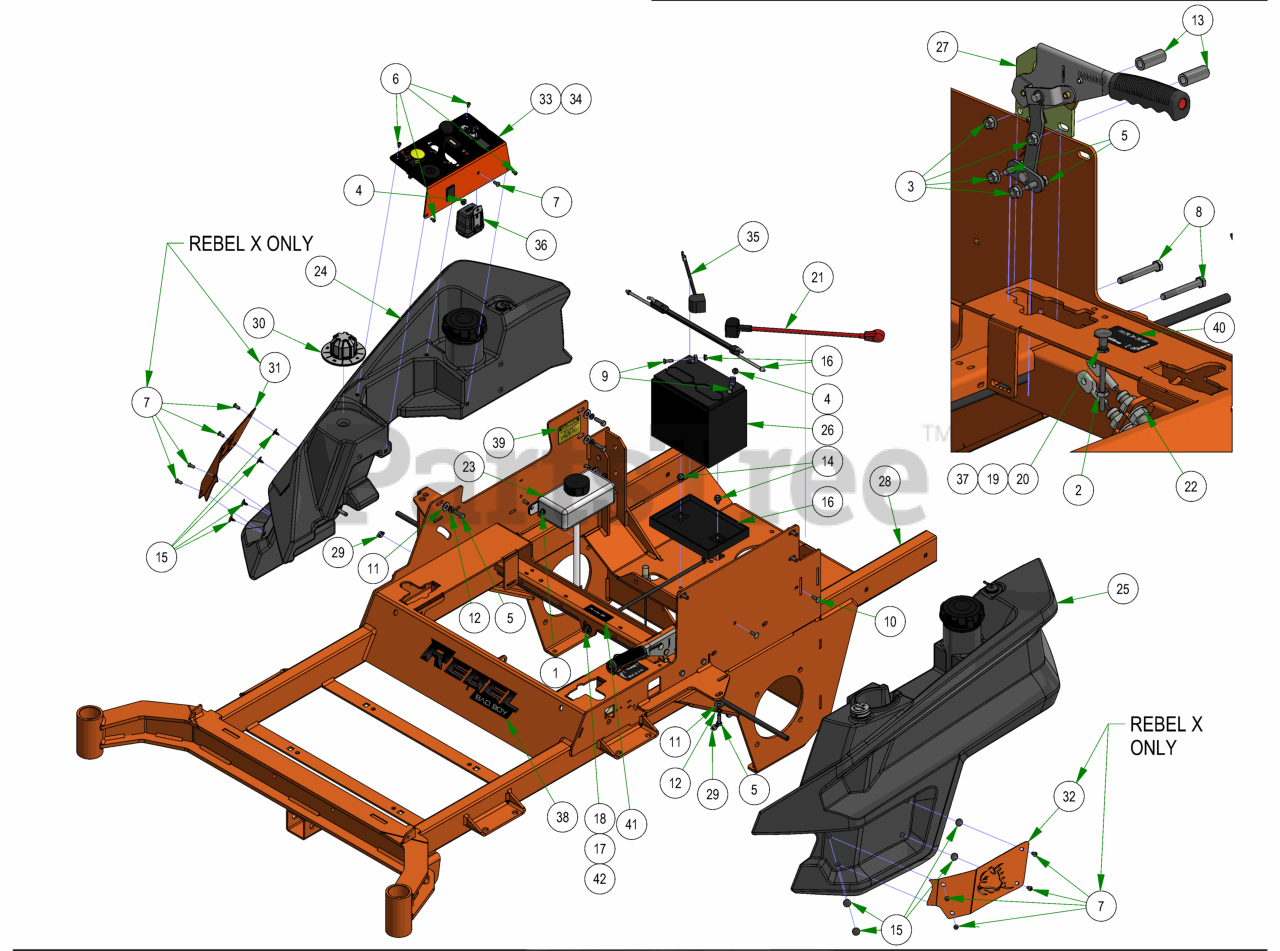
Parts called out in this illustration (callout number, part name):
1	1/4-20 NYL INSERT FLANGE LOCKNUT ZINC
2	3/8-24 HEX NUT ZINC YELLOW
3	5/16-18 NYLON INSERT FLANGE LOCKNUT ZINC
4	1/4-20 HEX SERRATED FLANGE NUT HARD/ZINC
5	5/16-18 X 1 HEX CAP SCREW (GR.5) ZINC
6	10-32 X 3/8 BUTTON SOCKET CAP SCREW 18-8 STAINLESS STEEL
7	1/4-20 X 1/2 BUTTON SOCKET CAP SCREW 18-8 STAINLESS STEEL
8	5/16-18 X 2-1/2 HEX CAP SCREW (GR.5) ZINC
9	1/4-20 X 3/4 HEX CAP SCREW (GR.5) ZINC
10	1/4-20 X 3/4 CARRIAGE BOLT (GR.5) ZINC
11	5/16 USS FLAT WASHER (7/8 OD) ZINC
12	5/16 SPLIT LOCKWASHER ZINC
13	.380 ID X .625 OD X 1.500 LGTH 2019 OUTLAW BRAKE HANDLE SPACER ZINC
14	5/16-18 X 1/2 HWH unslot (F) tcs zinc
15	3/16 x .48 Christmas Tree Nylon Black
16	2023 Battery Hold Down Assembly
17	2023 R-Series Fuel Line for Kohler
18	2023 Rebel Rogue Renegade Fuel Line for Kawasaki
20	Choke for 36Hp Vanguard & FX1000 Kawasaki
21	14" Red Battery Cable
22	Long Brake Cable
23	2019 Rebel Hydro Tank Assembly
24	2019 Right Rebel, Rogue, Renagade Fuel Tank (GAS)
25	2019 Left Rebel, Rogue, Renegade Fuel Tank (GAS)
26	SP-35 Battery
27	2019 Brake Handle Assembly
28	2023 Rebel Frame - Painted
29	2 EAR CLAMP 12.5mm-15mm
30	2019 Rigid Deck Dial 1.5 to 5.5
31	2019 Outlaw Fuel Tank Insert - Right
32	2019 Outlaw Fuel Tank Insert - Left
33	Rebel/Rogue Control Panel Assy
34	2023 Rebel/Rogue Control Panel Assy-Drive by Wire
35	Starter Cable
36	2019 Wiring Harness-Rebel/Rogue
37	Code Indicator Light
38	Rebel back Plate & Front Decal
39	Hydraulic Decal
40	2018 Out/XP/Diesel Brake Decal
41	R-Series Shut Off Valve Decal
42	2024 Rogue Vanguard Fuel Line Assembly 15"
